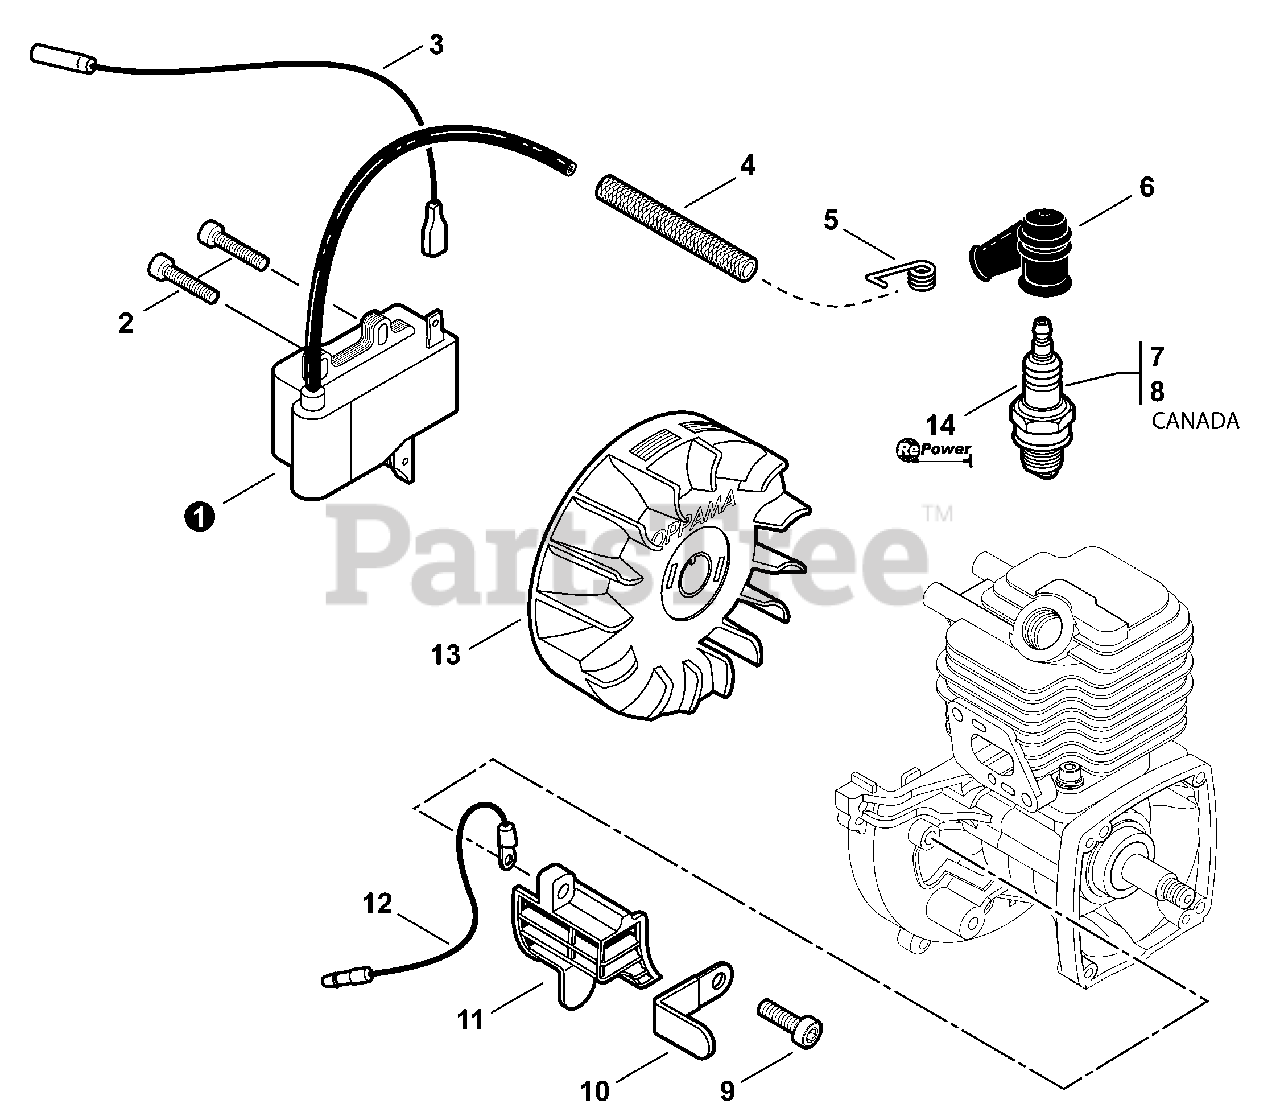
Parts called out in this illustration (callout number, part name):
1	COIL, IGNITION
2	BOLT, TORX 4×20
3	LEAD - IGNITION L= 210
4	PIPE, FUEL 7×8.6×65
5	TERMINAL, SPARK PLUG
6	CAP, SPARK PLUG
7	SPARK PLUG - BPM8Y
8	SPARK PLUG - BPMR8Y
9	BOLT, TORX 5×16
11	COVER, DUST
12	LEAD - GROUND L= 115
13	FLYWHEEL
14	TUNE-UP KIT - REPOWER
